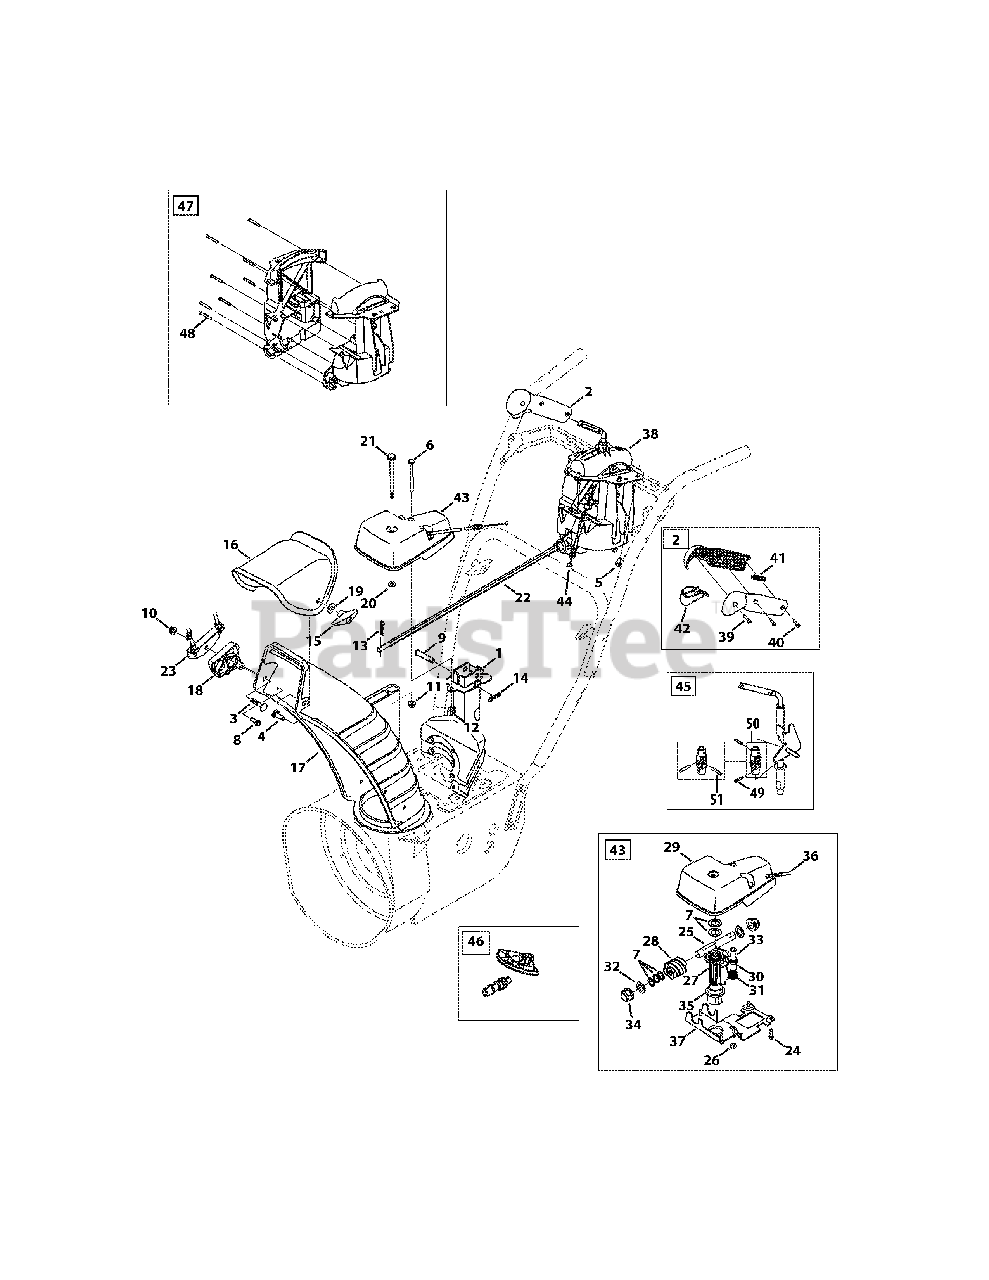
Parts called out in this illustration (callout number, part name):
1	Chute Support Bracket (small block)
2	Chute Control Trigger Kit, 2-Way & 4-Way
3	Bolt, Carriage, 5/16-18 x .750, 2-Way
4	Bolt, Carrier, 5/16-18 x 1.00
5	Screw, Hi-Lo, 1/4-15 x 0.50
6	Hex Head Screw, 1/4-20 x 3.00
7	Shim Washer, .632 x 1.00 x .010
8	Screw, Hi-Lo, 1/4-15 x 0.750
9	Clevis Pin, 3/8 x 1.87
10	Nut, Flange Lock, 5/16-18
11	Nut, Flange Lock, 1/4-20
12	Wing Nut, 1/4-20
13	Internal Cotter Pin
14	Bow-Tie Cotter Pin
15	Wing Knob, 5/16-18
16	Chute, Upper, 2-Way
17	Chute, Lower
18	Cable Guide, Chute Tilt
19	Washer, Flat, .349 x .879
20	Washer, Flat, .25 x .630
21	Screw, Shoulder, .312 x 3.5 x 1/4-20
22	Chute Rod, 3/8 Hex
23	Cable Bracket
24	Screw, 12-16 x .75
26	Hexlock Nut, 1/4-28
28	Worm
29	Gear Cover
31	Torsion Spring, .721 ID x .394
32	Washer, Flat, .625 x 1.0 x .067
33	Screw, Shoulder, .34 x .95 x 1/4-28
34	Hex Bearing
35	Flange Bearing
38	Chute Control, 2-Way
39	Screw, #8 x 1.00
40	Screw, 8-32 x .750
41	Joystick Plug
42	Joystick Trigger
43	Chute Rotation Gearbox
44	4-Way Cable
45	Shift Assembly, 2-Way
46	Gear Set Assembly
47	Handle Housing Assembly, 2-Way
48	Screw, #8-18 x 1.250
50	Block, Asm Joint
51	Pin, Roll
